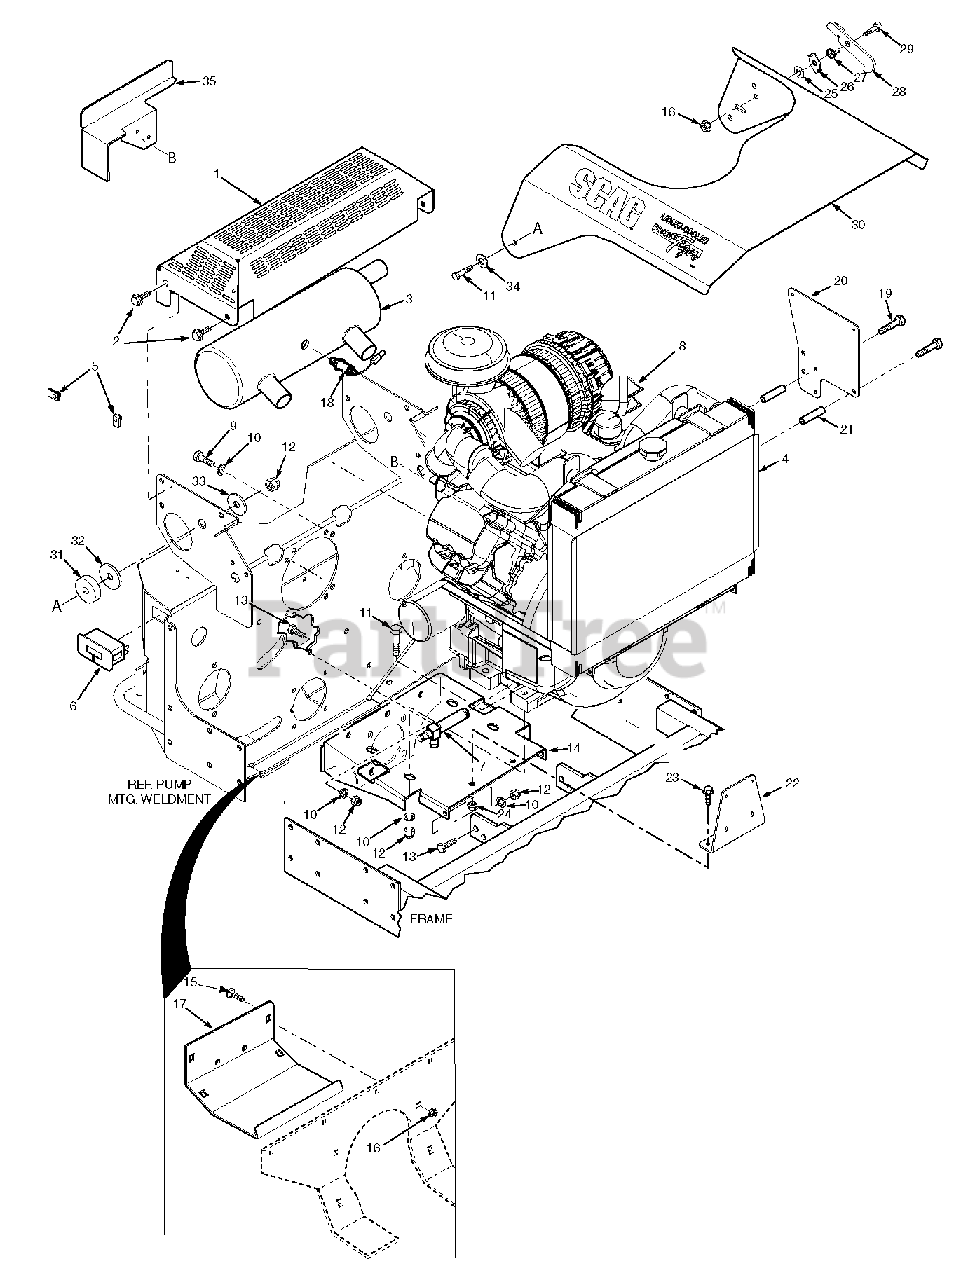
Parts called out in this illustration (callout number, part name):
1	Muffler Guard (Kohler)
2	Screw, Hex Serr. Flng. 1/4-20 x 3/4"
3	Muffler (Available only through Kohler)
4	Screen Weldment, Radiator (Kohler)
5	U-Nut, 1/4-20
6	Hour Meter
7	Oil Drain Extension
8	Engine, Kohler 31HP-EFI Aegis (Available only through Kohler)
9	Bolt, Hex Hd. 3/8-16 x 1"
10	Lockwasher, 3/8" Spring
11	Bolt, Hex Hd. 3/8-16 x 1-3/4"
12	Nut, Hex Elastic Stop 3/8-16
13	Bolt, Hex Hd. 3/8-16 x 1-1/4"
14	Plate, Engine Mounting
15	Bolt, Carriage 5/16-18 x 3/4"
16	Nut, Hex Serr. Flng. 5/16-18
17	Rear Cover
18	o2 Sensor (Available through Kohler Only)
19	Bolt, Hex Hd. M6-1.0 X 90mm
20	Mounting Bracket, ECU Kohler EFI
21	Spacer, ECU Mounting
22	Mounting Bracket, Fuel Pump Kohler EFI
23	Bolt, Hex Hd. 1/4-20 x 3/4"
24	Nut, Serr. Flng. 1/4-20
25	Flatwasher, 3/8-.406 x .812 x .065
26	Lock, Hood Latch
27	Spring, Hood Latch
28	Latch, Hood
29	Bolt, Shoulder 5/16-18 x 1/2"
30	Hood Assembly w/Decals
31	Spacer, Hood
32	Disc, Anti-Friction
33	Flatwasher, 3/8-.406 x 1.50 x 7 Gauge
34	Flatwasher, 3/8-.391 x .938 x .105
35	Heatshield, Throttle Cable
